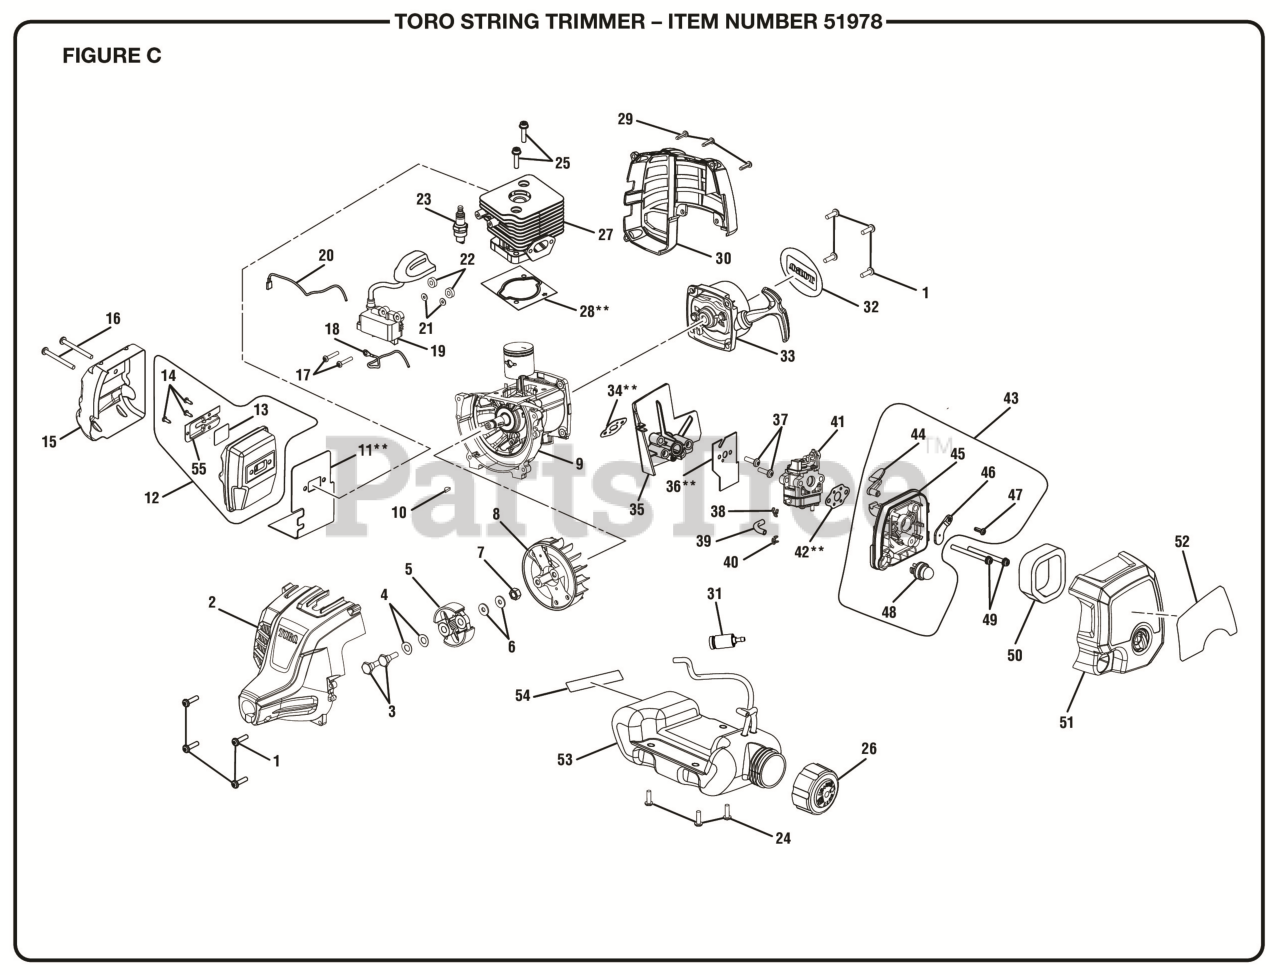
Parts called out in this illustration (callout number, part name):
1	Cap Screw w/Washer (M5 x 16 mm, T25 Torx Soc. Hd.)
2	Front Housing Assembly
3	Clutch Shoulder Bolt (M6 x 22.5 mm, Hex Hd.)
4	Washer (Curved)
5	Clutch Assembly
6	Washer (ID6 x OD15 x 1.2t)
7	Flange Nut (M8, Flywheel)
9	Crankcase Assembly.
10	WOODRUFF KEY (10 mm X 3 mm)
11	Muffler Gasket
12	Muffler Assembly
13	SCREEN
14	Screw (6-20 x 1/4 in., T20 Torx Pan Hd. S.T.)
15	HEAT SHIELD
16	Screw (M5 x 50 mm, Torx Slotted Recessed Pan Hd.)
17	Screw (M4 x 22 mm, T20 Torx Slotted Recessed Pan Hd.)
18	Lead Wire Assembly, Red
19	Coil Boot Assembly
20	Lead Wire Assembly, Black
21	Flat Washer (OD10 x ID42 x 1t)
22	Phenolic Spacer (Ignition Module)
23	SPARK PLUG (CHAMPION RCJ4)
24	Shoulder Screw w/Washer (M4 x 14 mm, T25 Torx Truss Hd.)
25	Screw (M5 x 22 mm, T25 Torx Soc. Hd.)
26	Fuel Cap Assembly
28	Gasket
29	Screw (M4 x 18 mm, T20 Torx Pan Hd. S.T.)
30	Rear Engine Housing
31	Fuel Filter
32	Logo Label (Rear)
33	Starter Recoil & Starter Cup Assembly
34	Heat Dam Insulator
36	Gasket
37	Screw w/Washers (M5 x 30 mm, T25 Torx Pan Hd.)
38	Clip-hose (Id 4.9)
39	Fuel Line (45 mm)
40	CLIP-HOSE (ID 4.9)
41	CARBURETOR ASSEMBLY
42	Carburetor Gasket
43	Filter Housing Assembly
44	CHOKE LEVER
45	CARBURETOR PLATE
46	Screw (M4 x 12 mm, T20 Torx Pan Hd. S.T.)
47	Screw (M4 x 12 mm, Slotted Recessed Pan Hd.)
48	Primer Bulb Assembly
49	Screw (M5 x 44 mm,T25 Torx Hd. Carburetor)
50	Air Filter (Element)
51	Airbox Cover Assembly w/Label
52	Starting Instructions Label
53	Fuel Tank & Cap Assembly
54	Combustion Warning Label
55	Trimmer Outlet
